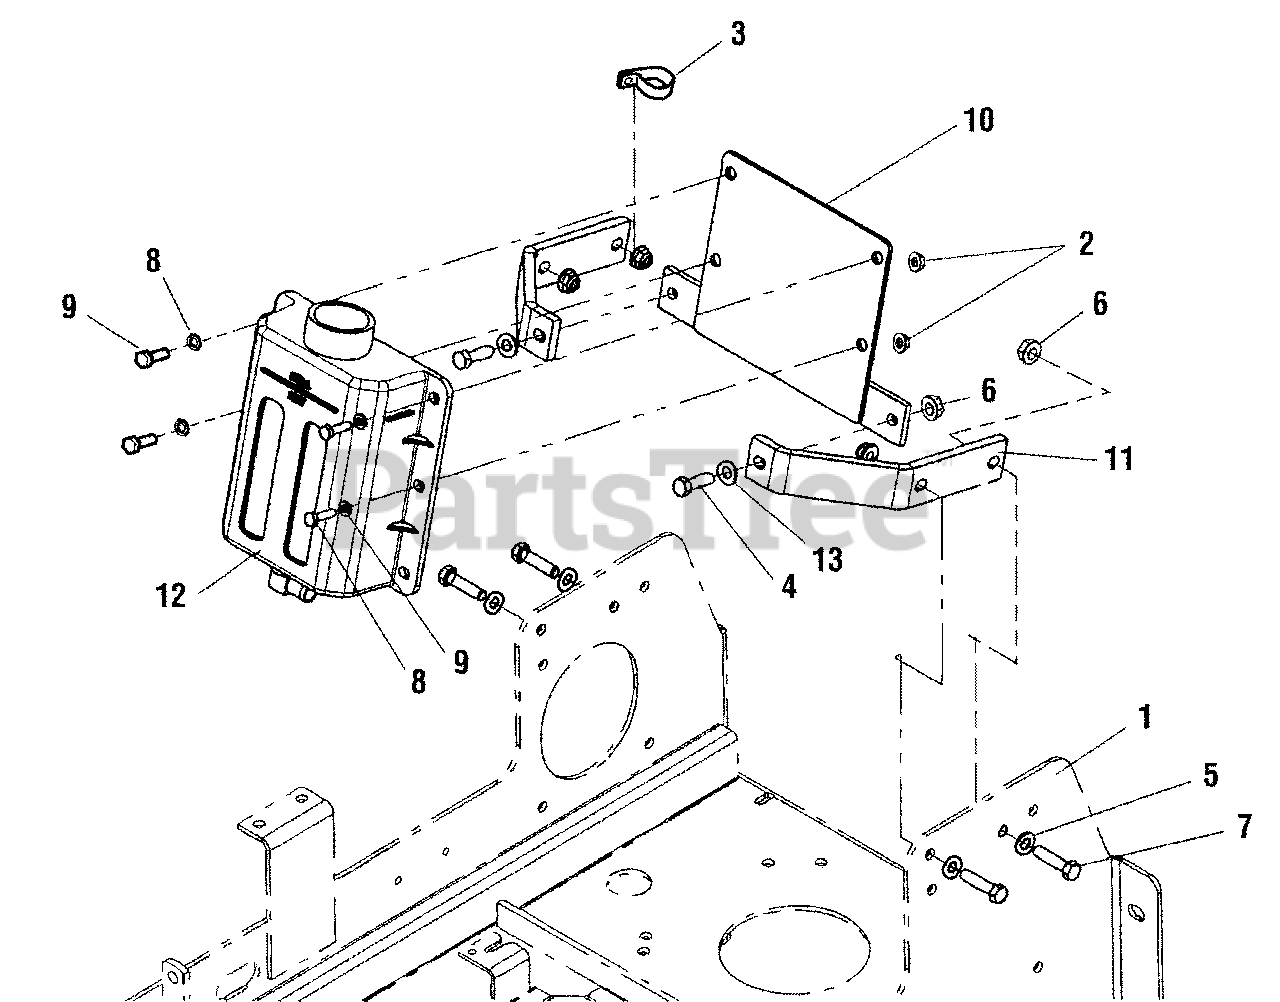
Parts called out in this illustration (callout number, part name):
1	MAIN FRAME
2	NUT, 1/4-20 HEX NYLOCK FLANGE (5025391)
3	CLAMP, VINYL, 1"
4	BOLT, 3/8-16 X 1-1/4"
5	WASHER, 3/8 SAE
6	NUT, 3/8-16 Hex Nylock Flange
7	BOLT, 3/8-16 X 1-1/2"
8	WASHER, 1/4 SAE (5025154)
9	BOLT, 1/4-20 X 1" GD5 CZ
10	HYDRAULIC TANK MOUNT
11	MOUNT BRACKET
12	HYDRAULIC TANK
13	WASHER, 3/8" GR. 9 FLAT
